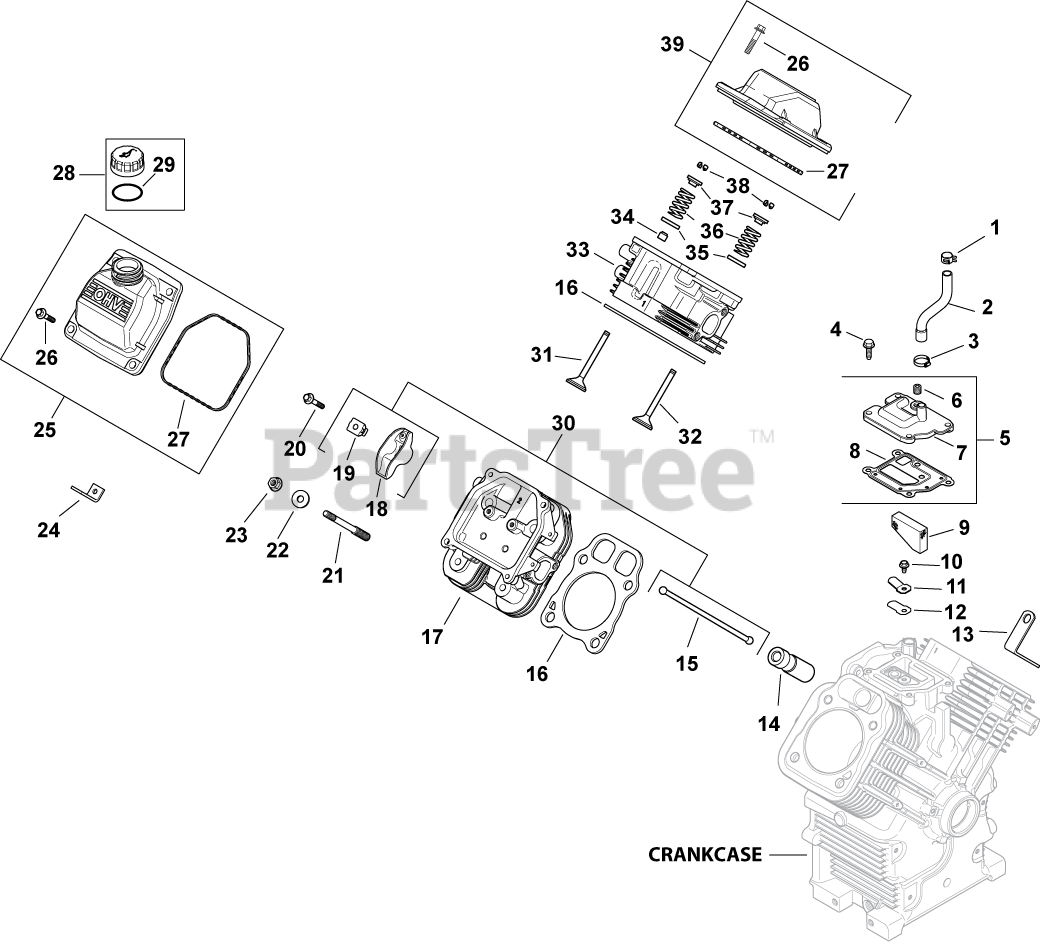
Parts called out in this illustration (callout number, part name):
1	CLAMP, BAND SPRING HOSE-(#2523737S)
2	HOSE, BREATHER
3	CLAMP, HOSE (KM)-USE 25 237 31-S
4	SCREW,FLG THD FRM M6X1.0X20-(#25086396S)
5	KIT, BREATHER ASSEMBLY
6	PLUG, CTSK PIPE 1/8"
7	COVER, BREATHER -USE 24 033 01-S
8	GASKET, BREATHER-USE 24 041 67-S
9	FILTER, BREATHER
10	SCREW, FLG THD FRM M5X.8X10
11	RETAINER, REED
12	REED, BREATHER
13	STRAP, LIFTING-USE 25 445 03-S
14	LIFTER, HYDRAULIC VALVE-USE 25 351 10-S
15	ROD, PUSH
16	CYL HEAD GASKET KIT-USE 24 841 04-S
17	HEAD, SERVICE ASSY CYL #2-USE 24 318 114
18	ARM, ROCKER
19	PIVOT, ROCKER ARM
20	SCREW, FLG M6X1.0X34
21	STUD, M8X1.25
22	WASHER, FLAT 8.6 MM
23	NUT, FLG M8X1.25
25	KIT, VALVE COVER-OIL FILL
26	SCREW, FLG M6X1.0X30
27	O-RING (YELLOW), VALVE COVER
28	KIT, OIL FILL CAP (YELLOW)
29	O-RING, DIPSTICK
30	KIT, VALVE TRAIN
31	VALVE, INTAKE (STD)
32	VALVE, EXHAUST (STD) - USE 32 016 01-S
33	HEAD, SERVICE ASSY CYL #1-USE 24 318 106
34	SEAL, VALVE STEM - (#2503214S)
35	RETAINER, SPRING
36	SPRING, VALVE
37	RETAINER, VALVE SPRING - USE 25 173 28-S
38	KIT, RETAINER
39	KIT, VALVE COVER-PLAIN
2401602-S	VALVE, EXHAUST (.25)
2401702-S	VALVE, INTAKE (.25)
